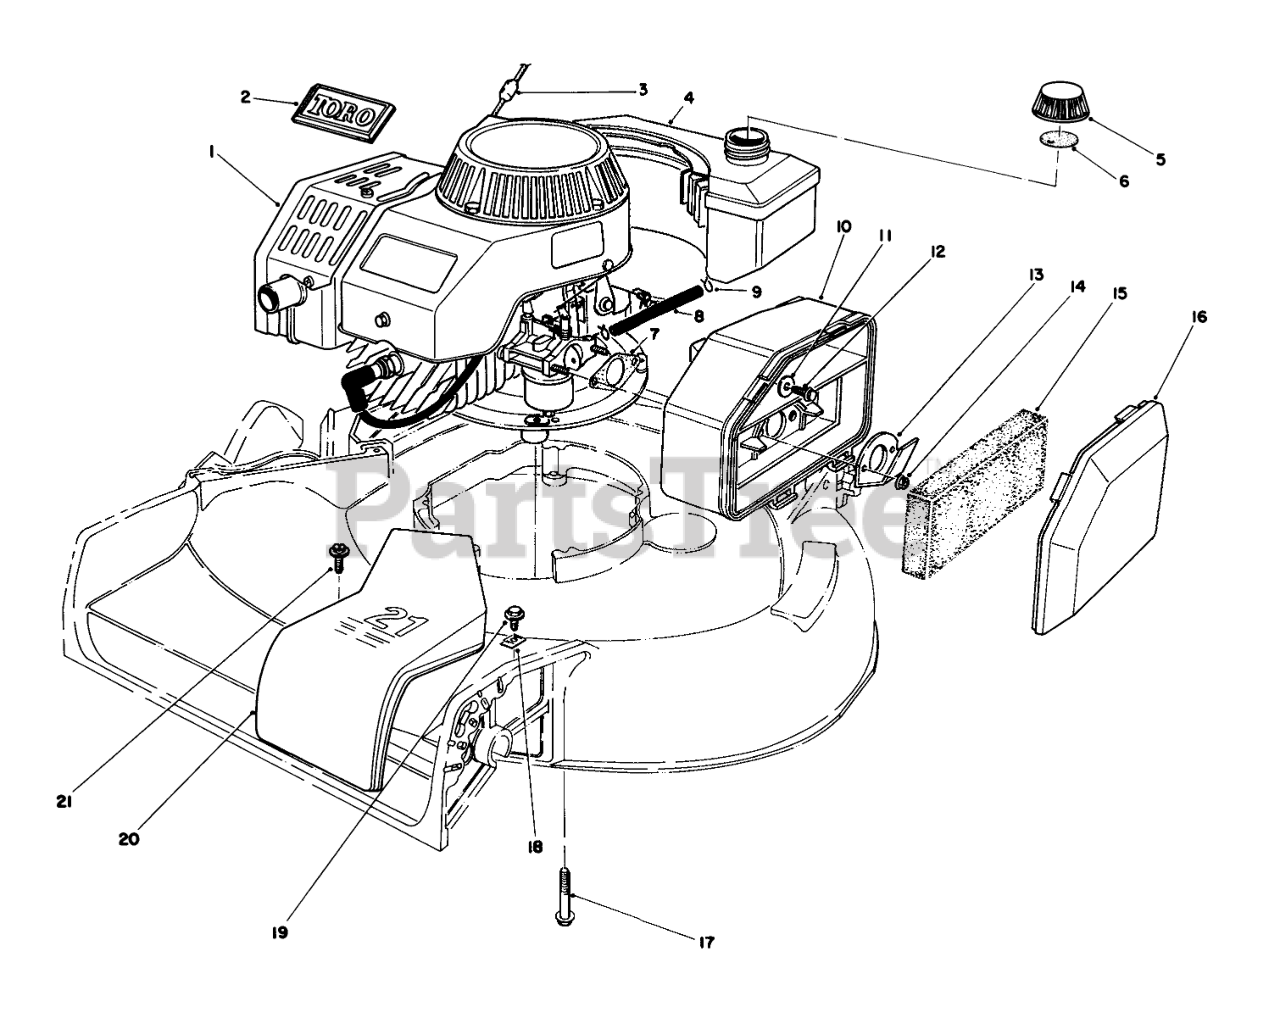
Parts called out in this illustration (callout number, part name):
1	Engine
2	TORO LOGO PLT
3	STOP-ROPE
4	Fuel Tank Assembly
5	Gas Cap Assembly (Incl. Ref. #6)
6	GAS CAP GASKET
7	GASKET-AIR CLEANER
8	FUEL LINE
9	CLAMP-HOSE
10	AIR CLEANER
11	WASHER-FLAT
12	SCREW-HH
13	SPIT BACK DEFLECTOR
14	NUT-LOCK
15	FILTER
16	AIR CLEANER COVER
17	FLG SCREW,3/8-16X2.000
18	Cable Clamp
19	Screw-Self Tapping
20	BELT COVER 21" S D
21	SCREW
